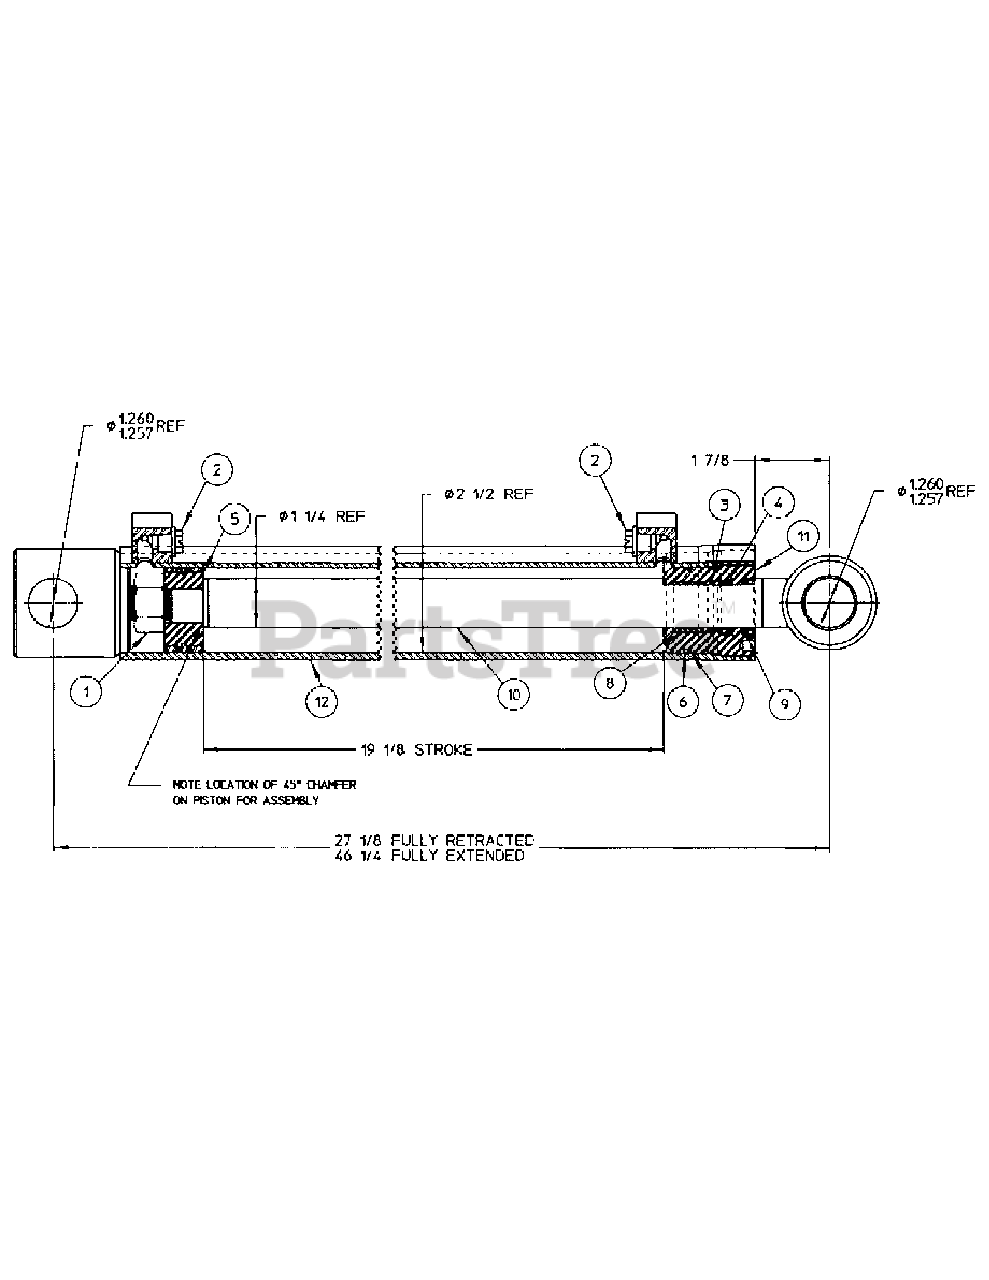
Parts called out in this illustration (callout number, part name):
1	NUT, 7/8 NF LOCK
3	O-RING, 2-9/16''OD X 2-3/8''ID
4	BACK-UP RING, 2.565''OD X 2.393'' ID
6	STEP SEAL
7	ROD SEAL
8	WEAR RING
9	ROD WIPER
10	PISTON ROD WELDMENT
11	GLAND WITH O-RINGS , BACK-UP, ETC.
12	CYLINDER TUBE WELDMENT
